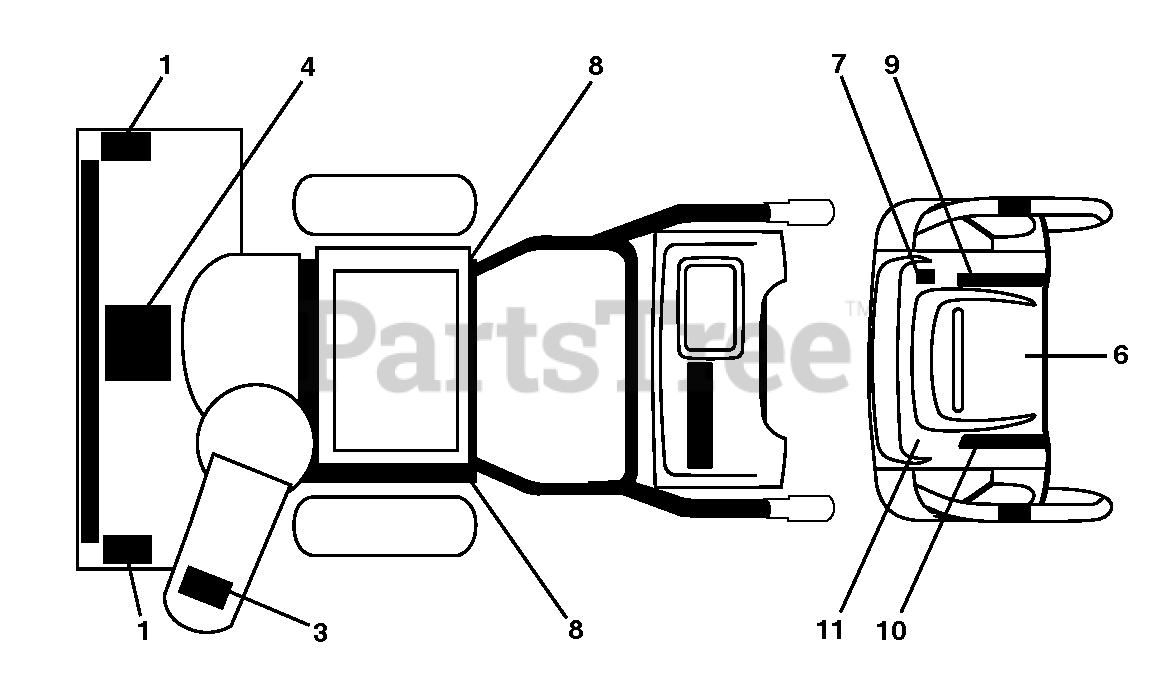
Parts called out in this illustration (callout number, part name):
1	DECAL.AUGER.SAFETY.
3	DECAL.CHUTE.SAFETY.
4	DECAL.AUGER."
7	DECAL.CONSOLE.HAND.WARMER
8	DECAL.BELT.GUARD.
9	DECAL CONSOLE DECAL DECAL.SNOW
10	DECAL CONSOLE DECAL DECAL.SNOW
11	DECAL,HEIGHTADJUST
